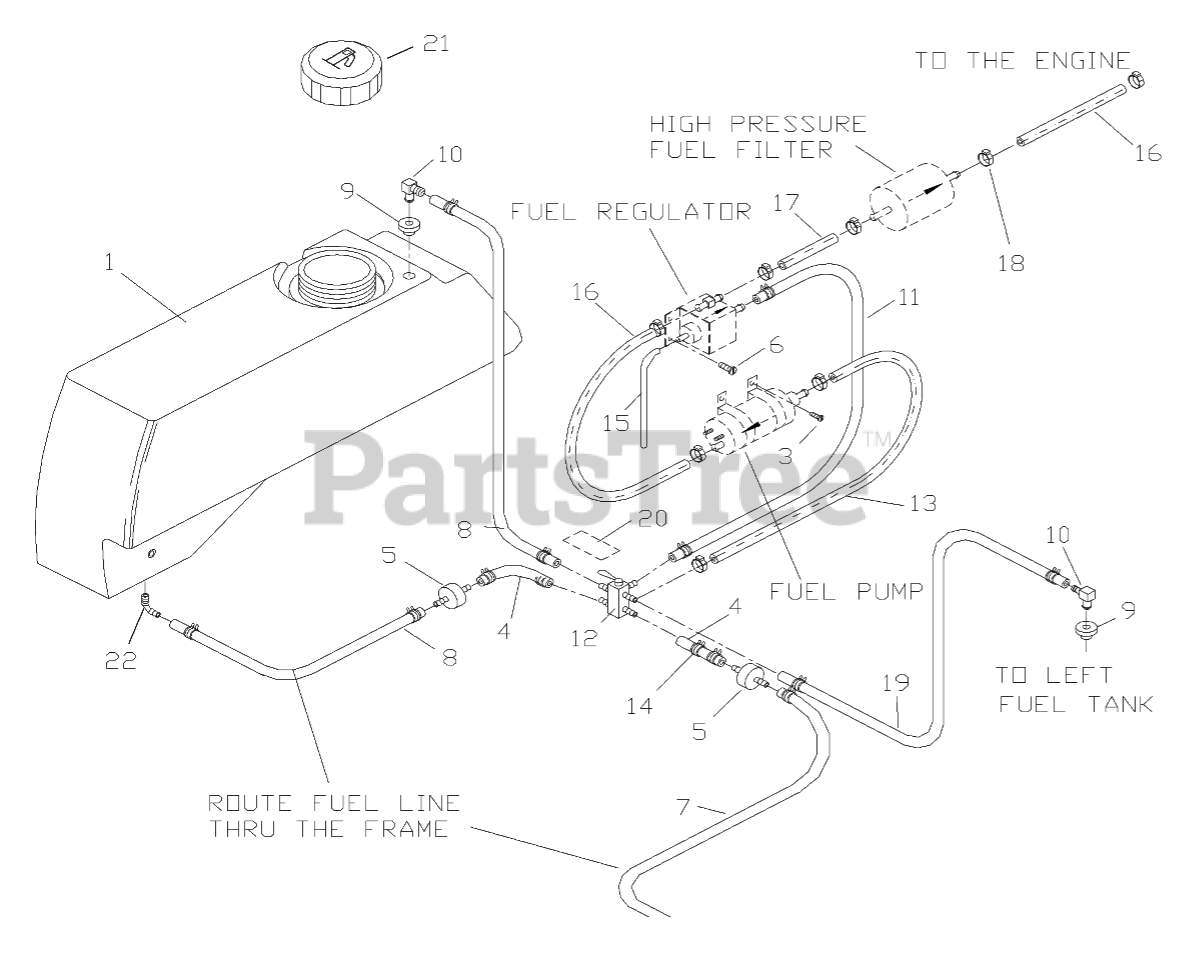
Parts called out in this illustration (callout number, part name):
1	FUEL TANK RT.
2	FUEL TANK LT.
3	SCREW SELF TAP
6	HCS 1/4 SELF TAP
7	FUEL LINE
8	FUEL LINE
9	RUBBER GROMMET
11	FUEL LINE
12	FUEL VALVE
14	HOSE CLAMP
21	FUEL CAP
22	TANK FITTING, 90°
